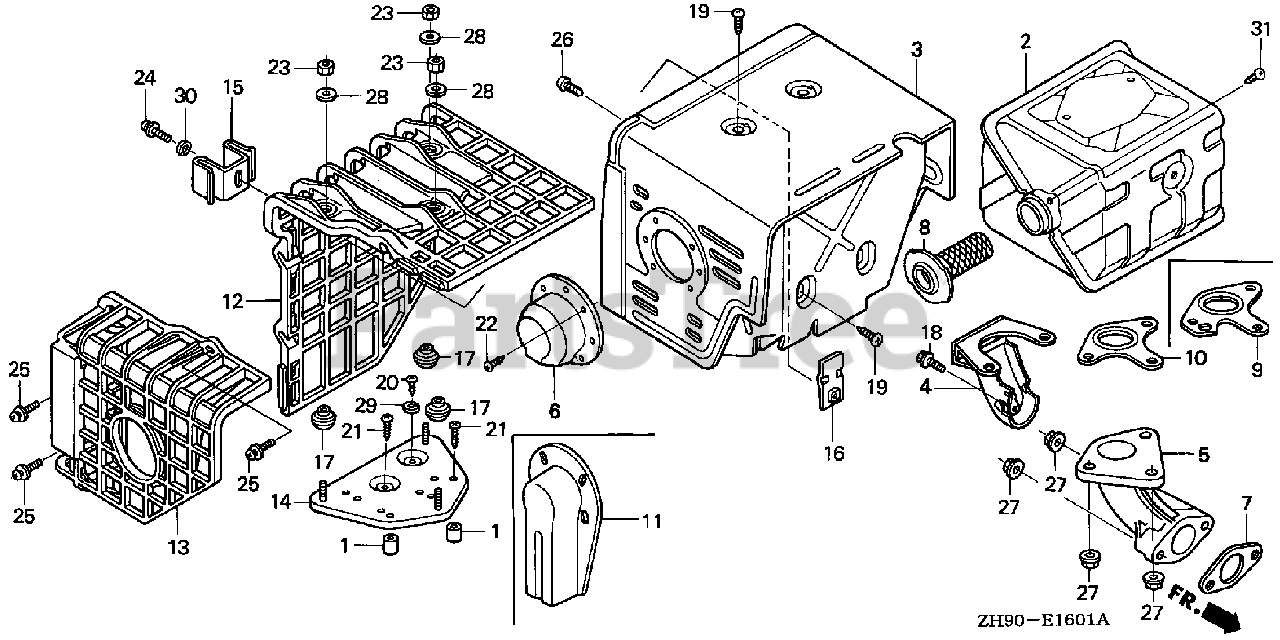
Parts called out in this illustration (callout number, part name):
2	MUFFLER (100DB)
3	PROTECTOR, MUFFLER
5	PIPE, EX.
6	CAP, MUFFLER
7	GASKET, EX. PIPE
8	ARRESTER, SPARK
9	GASKET, MUFFLER (ARRESTER)
10	GASKET, MUFFLER
19	SCREW, TAPPING (5X8)
22	SCREW, TAPPING (4X6)
26	SCREW, TAPPING (6X10)
27	NUT, FLANGE (8MM)
31	SCREW, TAPPING (4X6)
